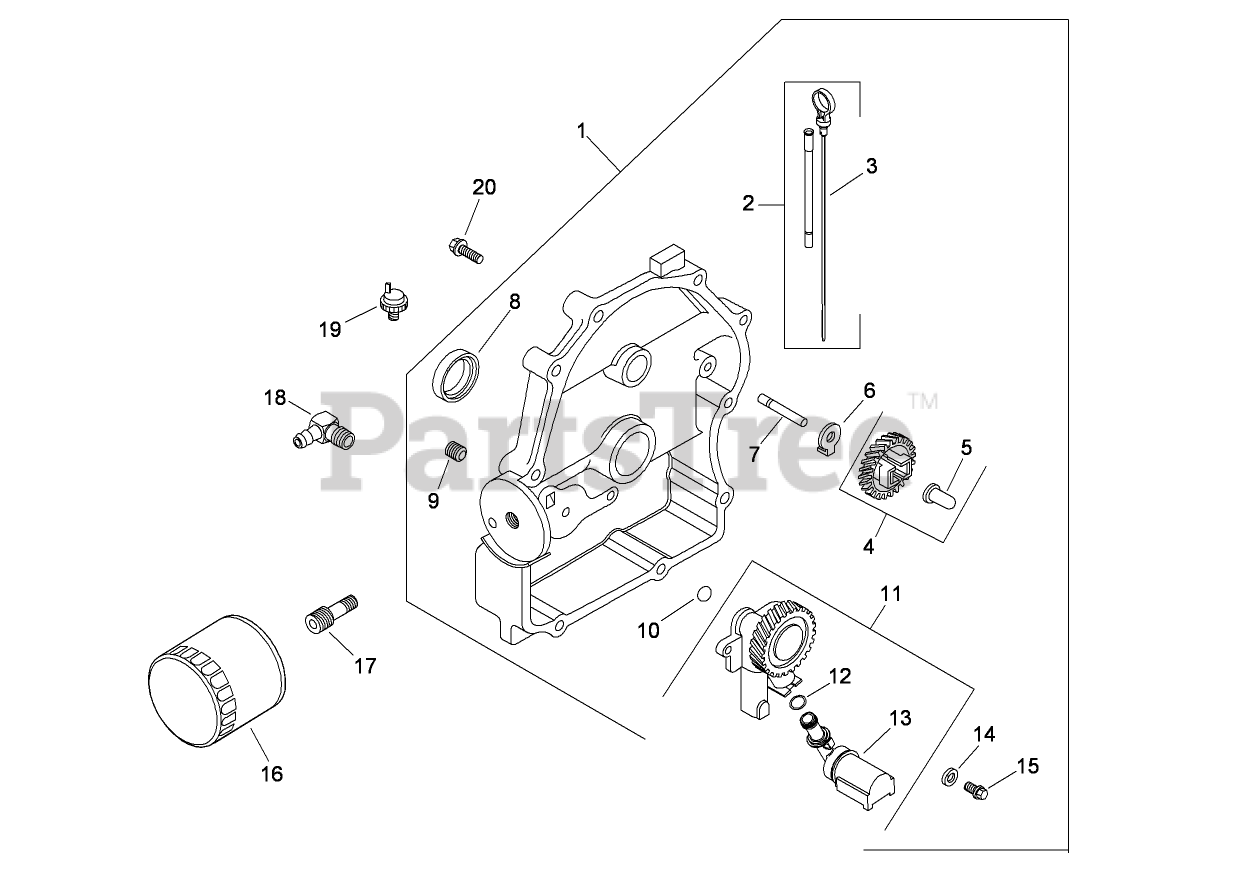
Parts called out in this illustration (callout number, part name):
1	Closure Plate ASM (Includes 2-15)
2	Dipstick Tube ASM (Includes 3)
3	Dipstick
4	Governor Gear Kit (Includes 5)
5	PIN-REGULATING, GOVERNOR
6	TAB-LOCKING
7	SHAFT-GEAR, GOVERNOR
8	SEAL-OIL
9	PLUG-PIPE, COUNTERSUNK (1/8)
10	O-Ring
11	Oil Pump ASM (Includes 12, 13)
12	O-Ring (Oil Pick up)
13	TUBE-PICK UP, OIL
14	WASHER-FLAT (6 MM)
15	SCREW-FLANGE, THREAD FORMING (M6X1.0X25)
16	Filter-Oil
17	Nipple-Filter, Oil
18	Connector-Hose, 90 Deg
19	SWITCH-PRESSURE, OIL
20	SCREW-FLANGE (M8X1.25X45)
